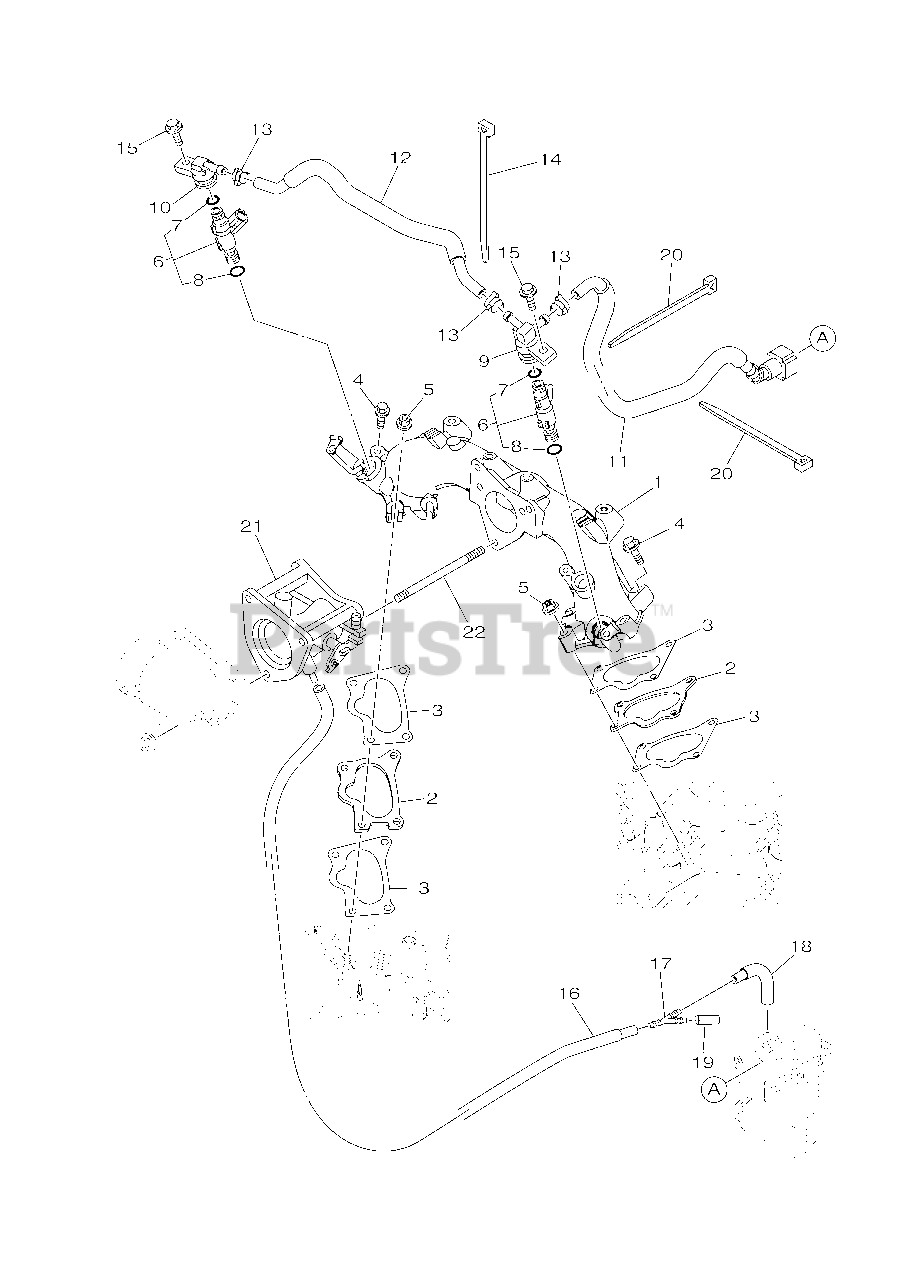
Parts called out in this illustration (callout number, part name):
1	MANIFOLD
2	JOINT, CARBURETOR 1
4	BOLT, FLANGE
5	NUT, FLANGE
6	INJECTOR
10	PIPE, INLET 2
11	PIPE,FUEL INJECTION 1
12	PIPE, FUEL INJECTION 2
15	BOLT, FLANGE
19	CAP, JOINT
21	THROTTLE BODY ASSY
22	BOLT, STUD
